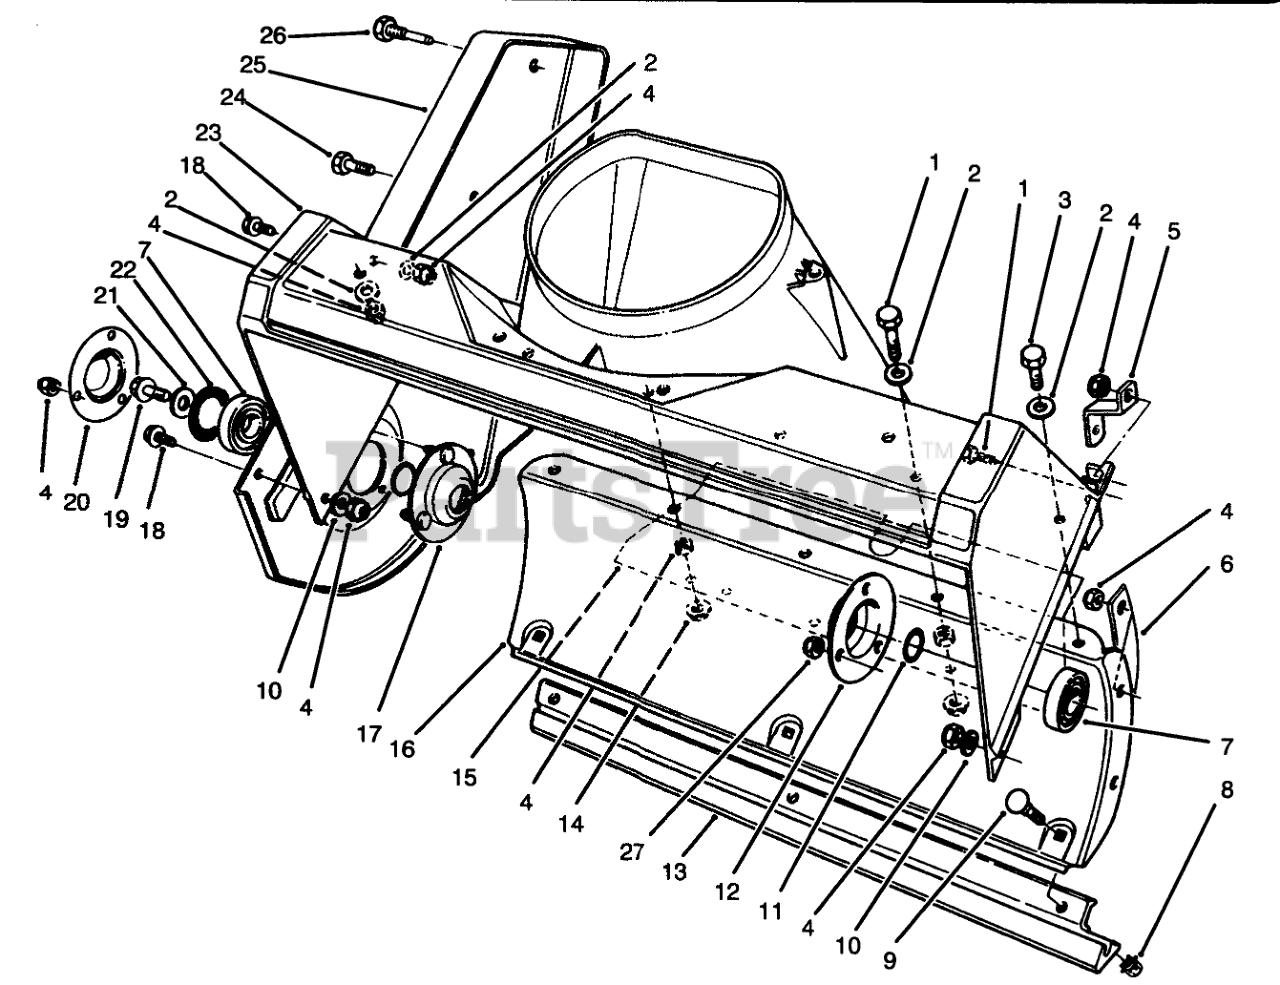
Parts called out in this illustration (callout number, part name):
1	SCREW-HH
2	WASHER-FLAT
3	SCREW-HH
4	NUT-LOCK, NI
5	BRACKET-HOUSING
6	BRACKET-HOUSING, LOWER
7	BEARING-BALL
8	NUT-KEPS
9	SCREW-CARR
10	WASHER-FLAT
11	WASHER-THRUST
12	FLANGE-BEARING
13	SCRAPER
14	NUT-LOCK, HHF
15	COVER-BOTTOM
16	Housing-Lower
17	FLANGE-BEARING
18	SCREW-HWH
19	SCREW-HHF
20	Trough
21	WASHER-FLAT
22	WASHER-RUBBER
23	HOUSING
24	SCREW-HH
25	Sideplate-RH
26	PIN-ROTOR
27	NUT-LOCK, NI
